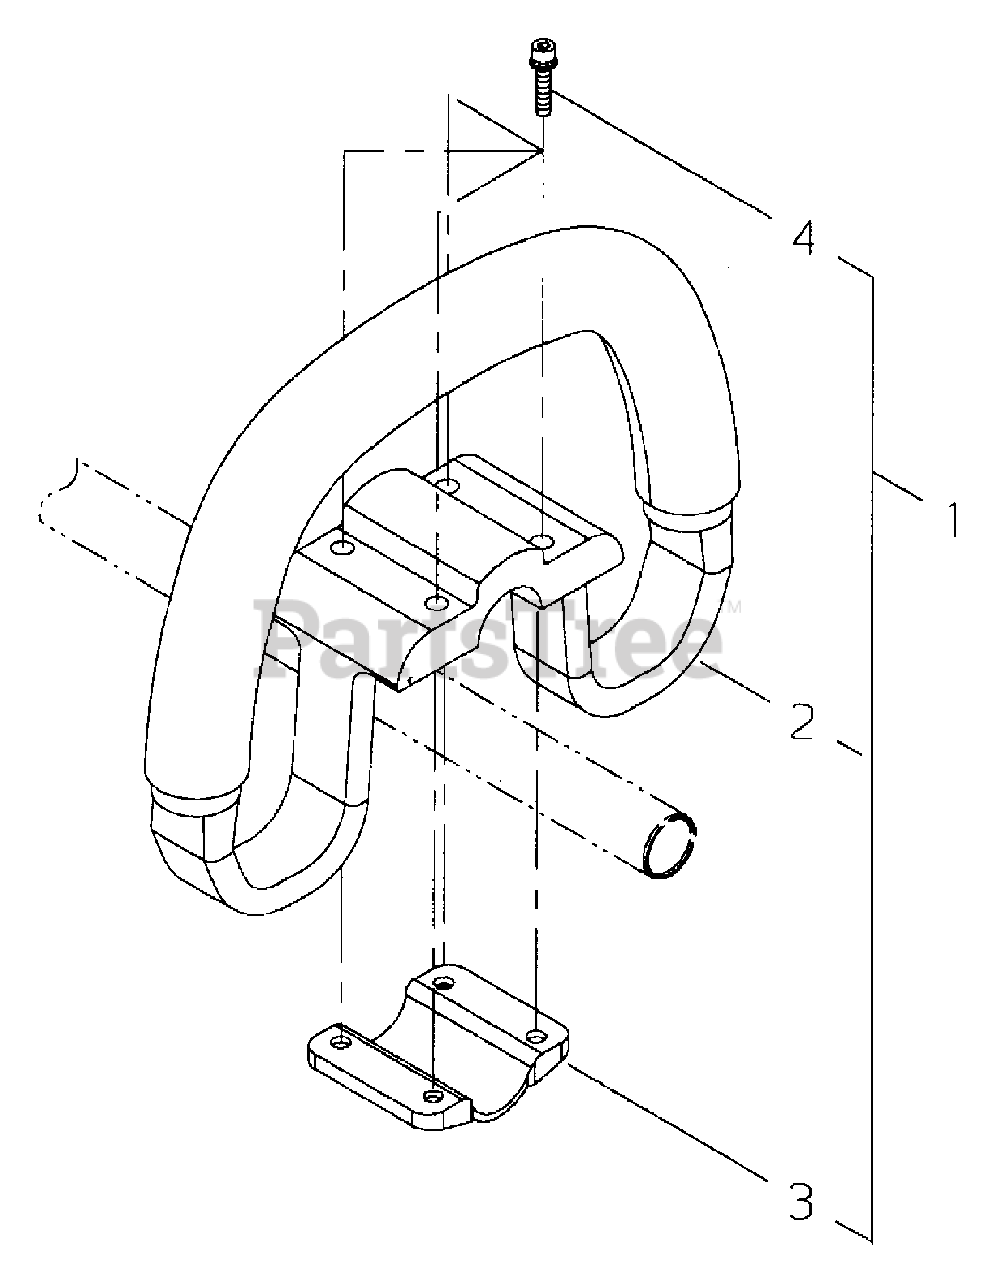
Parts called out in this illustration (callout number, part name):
1	HANDLE ASSY - SUPPORT
2	HANDLE
3	BRACKET, MOUNTING
4	BOLT M5×25
